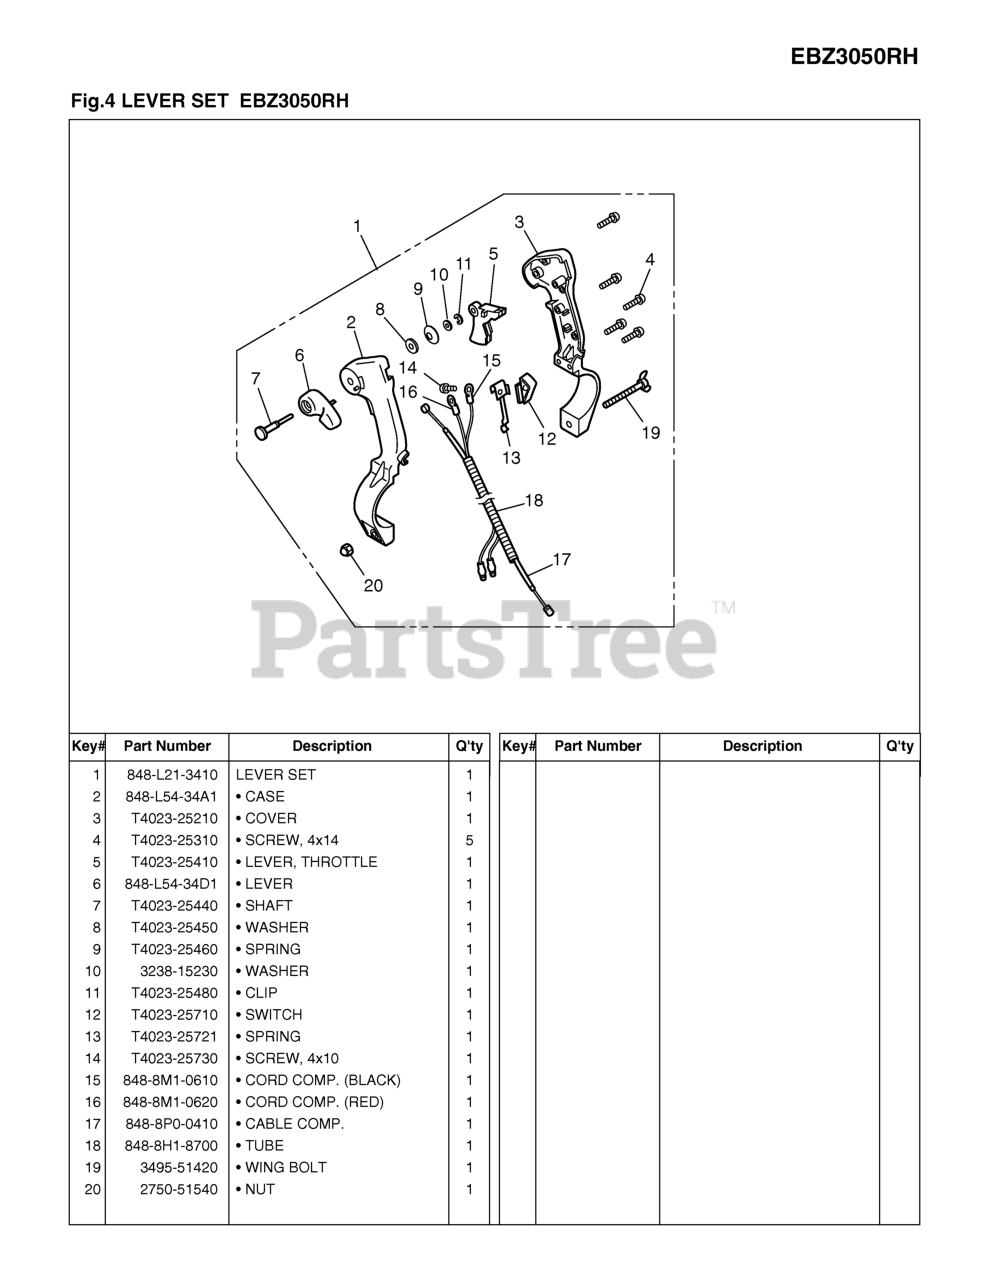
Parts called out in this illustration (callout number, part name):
1	LEVER SET
2	CASE
3	USE T402325211
4	SCREW 4X14
5	LEVER, THROTTLE
6	LEVER
7	SHAFT
8	WASHER
9	SPRING WASHER
10	WASHER
11	CLIP
12	SWITCH
13	SPRING
14	SCREW 4X10
15	CORD COMP-BLK
16	CORD COMP-RED
17	CABLE COMP
19	BOLT, WING
20	NUT
